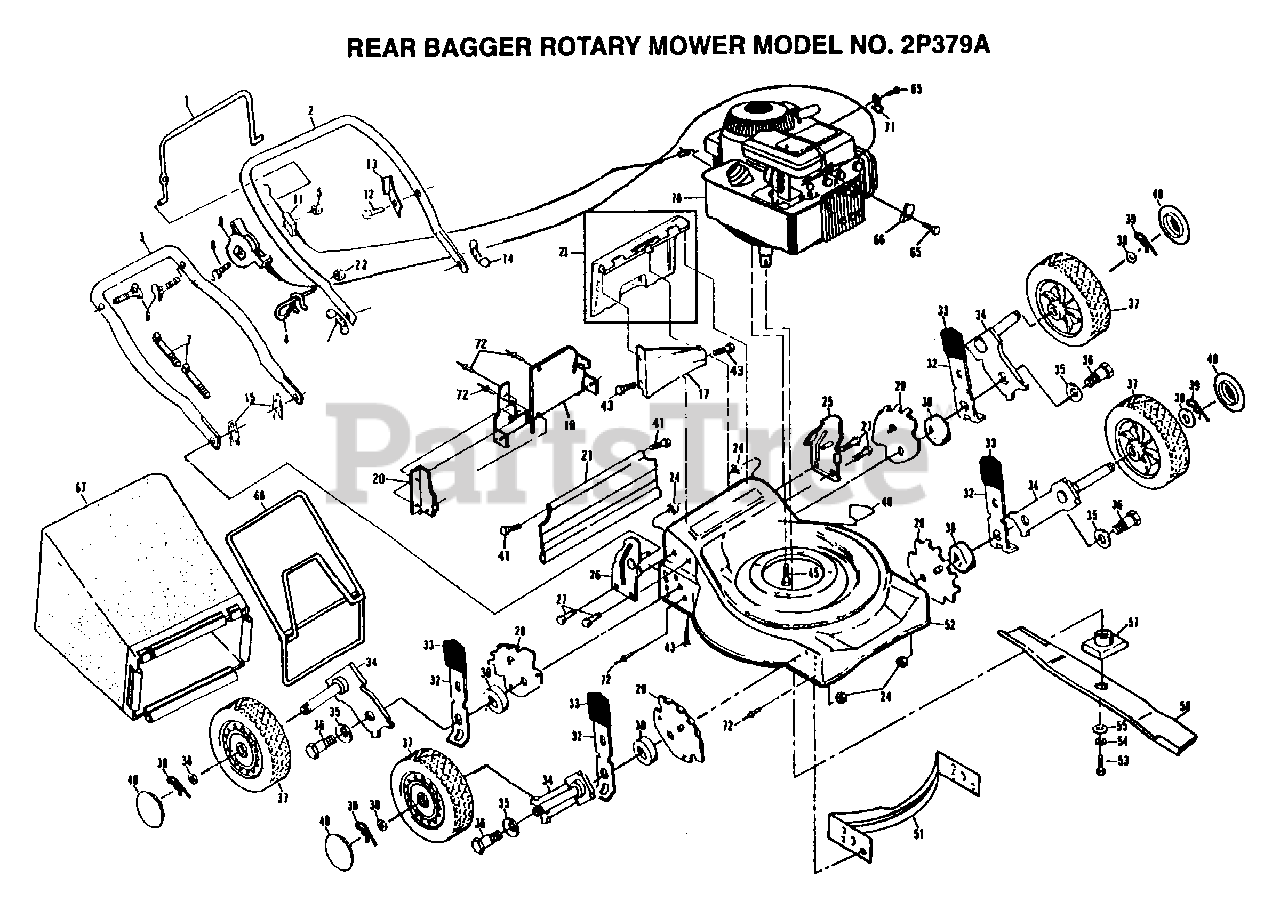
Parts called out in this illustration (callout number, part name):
1	CONTROL BAR
4	ROPE GUIDE
6	BOLT.HANDLE.LM
8	SCREW.HXHD.WASH.
9	CONTROL THROTTLE
11	"CABLE,ENG ZONE CO"
12	TAPPING SCREW
13	"BRKT,UPSTOP"
14	"NUT,WING PM"
15	HAIRPIN COTTER
16	DISCHARGE GUARD
17	REAR BAFFLE
18	SCREW PM
19	PLATE.BACK.20RD
21	SKIRT.PUSH.20RD
22	NUT
23	KIT.DOOR.RR.20STL
24	LOCKNUT PM
27	SCREW
29	BRACKET.ADJ.9POS.
32	SPRING SELECTOR
33	KNOB PM
34	AXLE ARM
35	"WASHER, BELLEVIL."
36	BOLT SHLD 3/8-16
38	WASHER
39	RETAINER CLIP PM
40	HUB CAP
41	HINGE SCREW
43	SCREW
45	SCREW
46	DECAL HYT
53	SCREW
54	LOCKWASHER
55	"WASHER,HARDEN"
57	BLADE ADAPTOR
65	SCREW PM
66	CABLE CLAMP
67	GRASS BAG
68	CATCHER FRAME
71	GUIDE CLIP PM
72	BLIND RIVET
